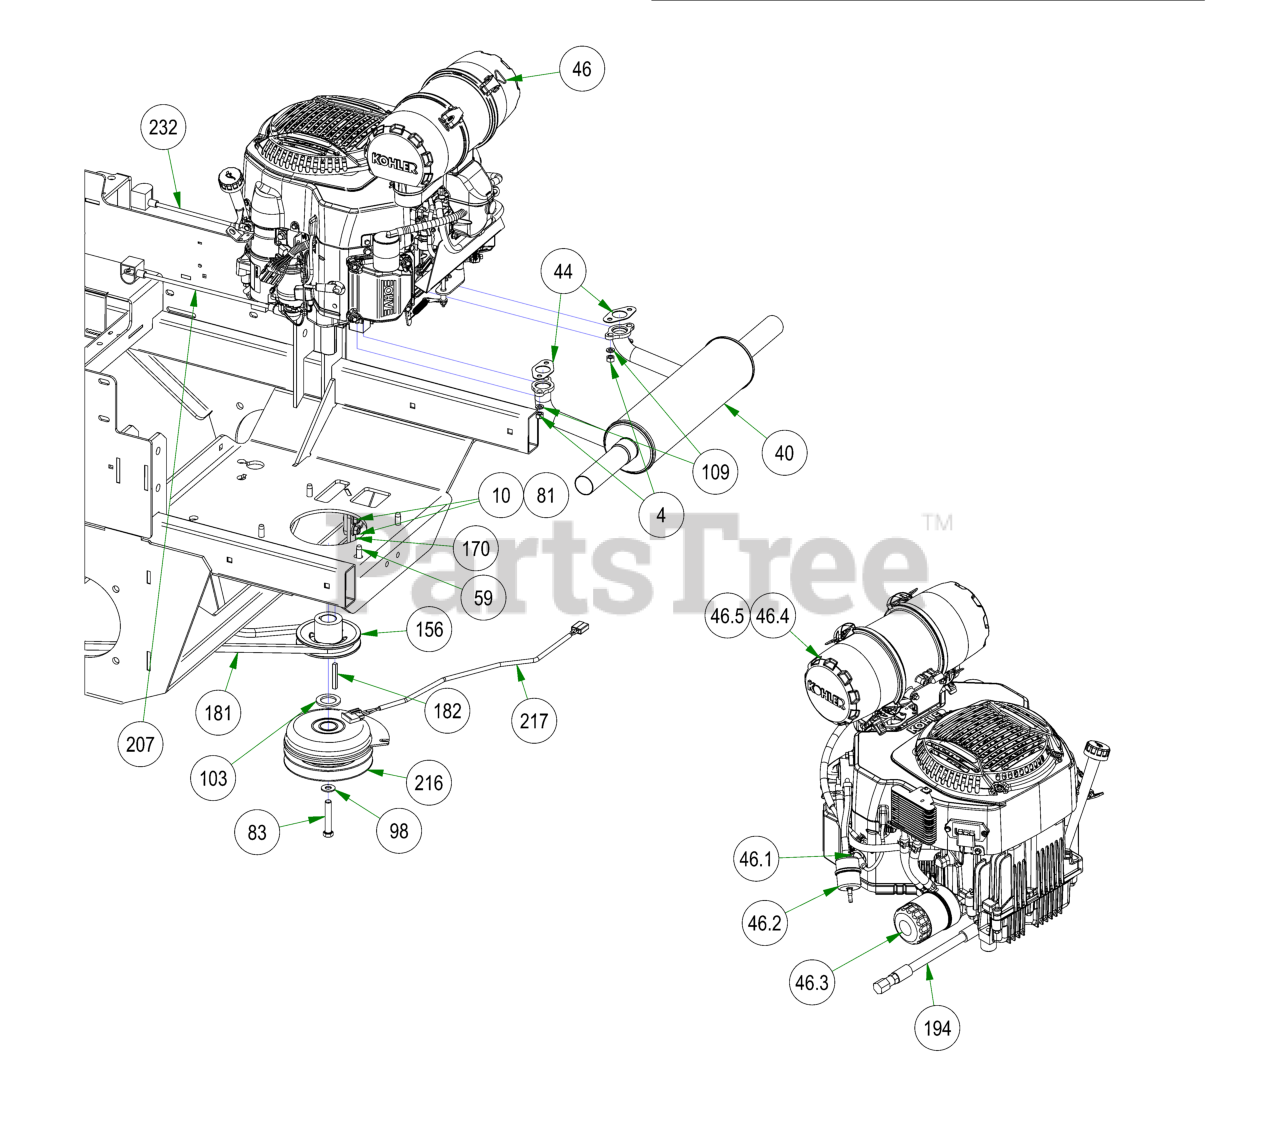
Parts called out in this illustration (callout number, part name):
4	M8-1.25 DIN 934 HEX NUT (CL.8) ZINC
10	3/8-16 NYLON INSERT FLANGE LOCKNUT (GR.F) ZINC
40	2019 Rebel Kohler CV752 Muffler
44	Exhaust Gasket
46	Kohler Command Engine
46.1	Spark Plug
46.2	25/26 HP Kohler Fuel Filter
46.3	Oil Filter
46.4	Canister Air Filter- Outer
46.5	Canister Air Filter- Inner
59	3/8-16 X 1-1/8HEX WASHER UNSLOT SERRATED (TRI-LOB) TRS
81	3/8-16 X 1 CARRIAGE BOLT (GR.5) ZINC
83	7/16-20 X 2-1/2 HEX Bolt GR 8 W/ Patch
98	3/8 FLAT WASHER USS (1" OD) ZINC
103	1.140 ID X 1.750 OD X .132 THICK FLAT WASHER PLAIN
109	5/16 SPLIT LOCKWASHER ZINC
156	4 3/4 Motor Pulley
170	Rebel Clutch Tab
181	2019 Rebel Pump Belt
182	1/4 X 2 SQ MACHINERY KEY 1018 STL PLAIN
194	Oil drain Hose
207	14" Red Battery Cable-Base Outlaw
216	Clutch Assembly
217	Clutch Pigtail
218	2022 Rebel Frame
232	Starter Cable
